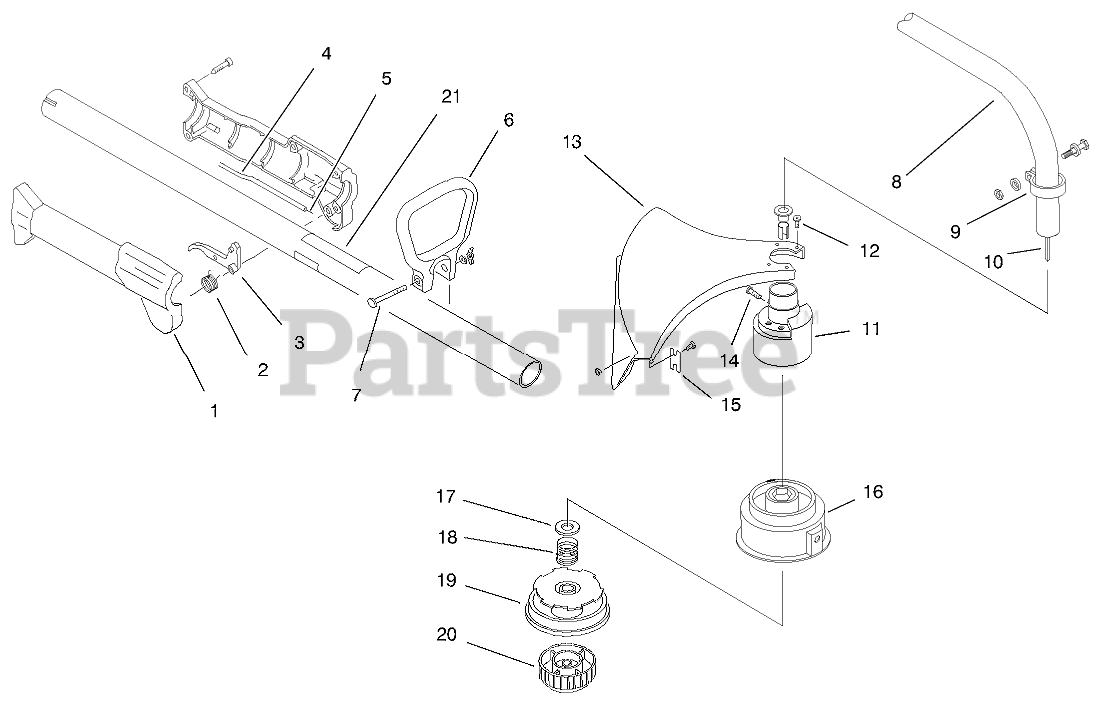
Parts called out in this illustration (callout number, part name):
1	Throttle Housing & Trigger Asm.
2	SPRING - TRIGGER
3	HSG - THROTTLE TRIGGER
4	Throttle Cable Housing
5	Throttle Cable
6	D-Handle
7	HARDWARE - D-HANDLE
8	DRIVE SHAFT HSG ASM
9	CLAMP ASM - UPPER
10	SHAFT - FLEX, 48.94
11	BUSHING HSG ASM
12	Guard Mounting Screw
13	Guard and Blade Asm. (Incl. Ref. #16)
14	Anti-Rotation Screw
15	BLADE ASM
16	OUTER SPOOL EYELET ASM
17	RETAINER WASHER(SET OF 10)
18	SPRING
19	REEL - INNER
20	SMALL BUMP KNOB ASM
21	DECAL - SAFETY SYMBOLS
